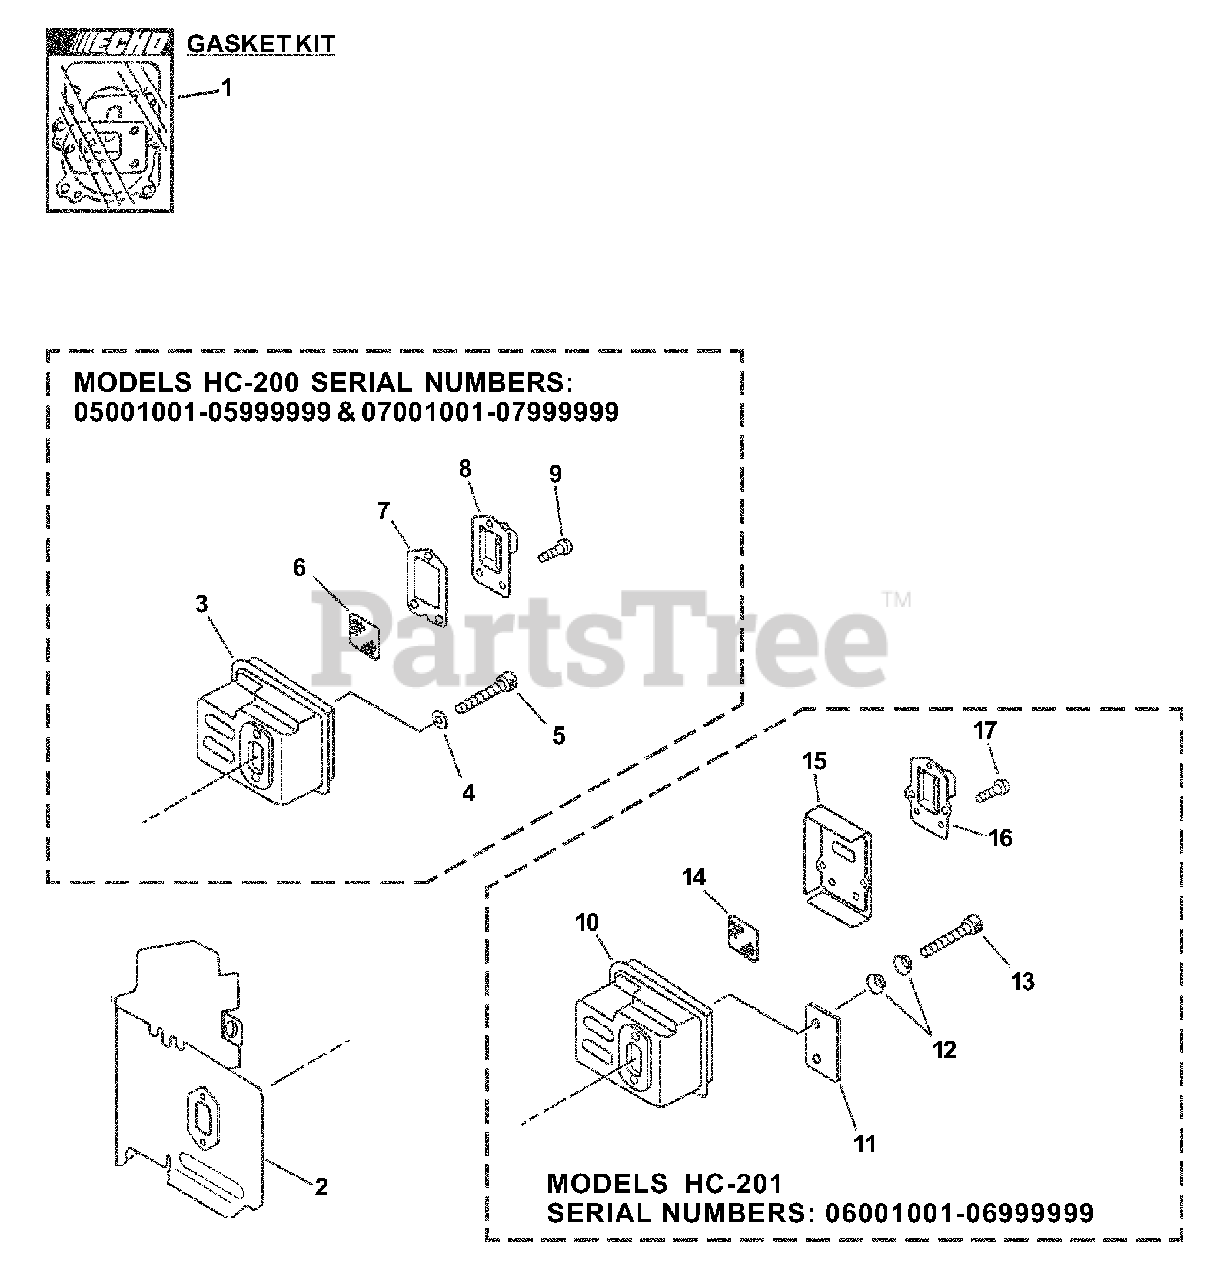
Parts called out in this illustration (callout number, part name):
1	GASKET KIT
2	SHIELD, EXHAUST
4	WASHER, FLAT 5.5×10×0.8
5	BOLT 5×55
6	SCREEN, SPARK ARRESTER
7	GASKET, EXHAUST
8	GUIDE, EXHAUST
9	SCREW 4×10
10	MUFFLER
11	PLATE, EYE
12	CONICAL WASHER
13	BOLT 5×55
14	SCREEN, SPARK ARRESTER
15	GASKET, EXHAUST
16	GUIDE, EXHAUST
17	SCREW 4×10
